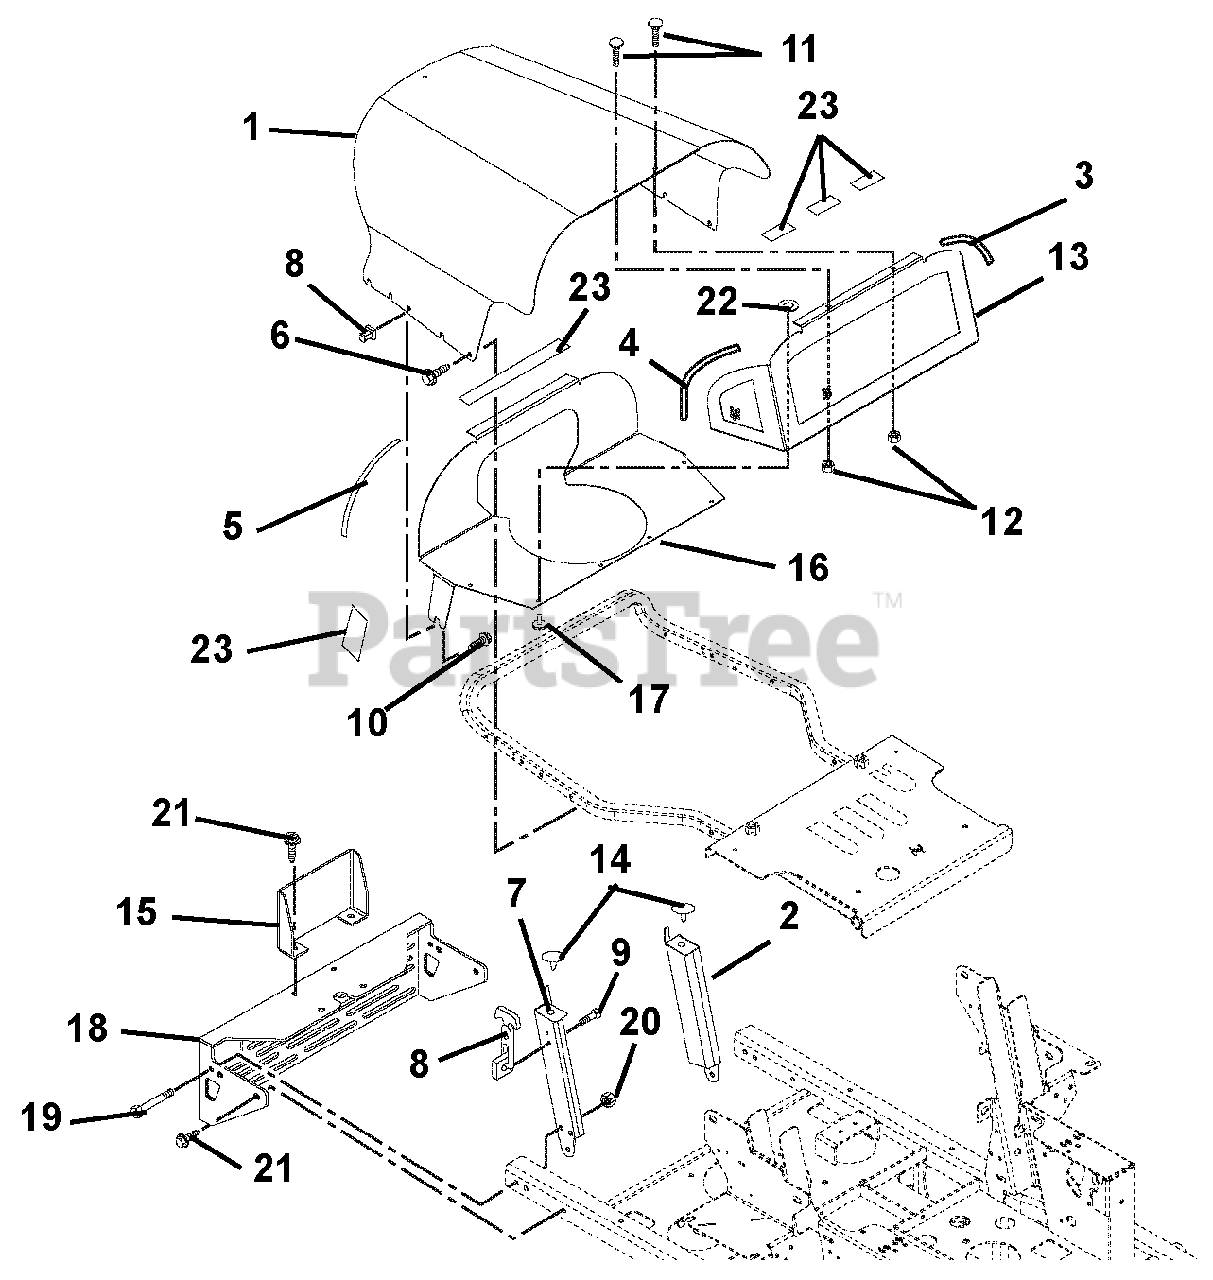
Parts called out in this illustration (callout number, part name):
2	Weldment, Hood Support, Left Hand
3	Seal, Trim Lok Bulk .06 Bubble
4	Seal, Trim Lok Bulk .06 Bubble
5	Seal, Trim Lok Bulk .06 Bubble (048)
6	Screw, Tapping .38-16 x .50 Hex Washer Head
7	Weldment, Hood Support Right Hand
8	Latch, Rubber
9	Screw, Machine 10-24 x .50 Hex Washer Head
10	Screw, Machine 10-24 x 1.50 Hex Washer Head
11	Bolt-Round Head Square Neck .25-20 x .50 Grade 5
12	Nut-Locking-Top-Flange .25-20
13	Weldment, Plenum
14	Button Bumper
15	Guard, Muffler
16	Support, Plenum
17	Rivet, Pop .18 x .402
18	Bumper, Rear
19	Bolt, Hex .38-16 x 2.75 Grade 5
20	Nut-Locking-Top-Flange .38-16
21	Screw, Tapping .38-16 x .75 Hex Washer Head
22	Washer-Flat-Steel .219 x .50 x .049
23	VHB Tape 4941F
